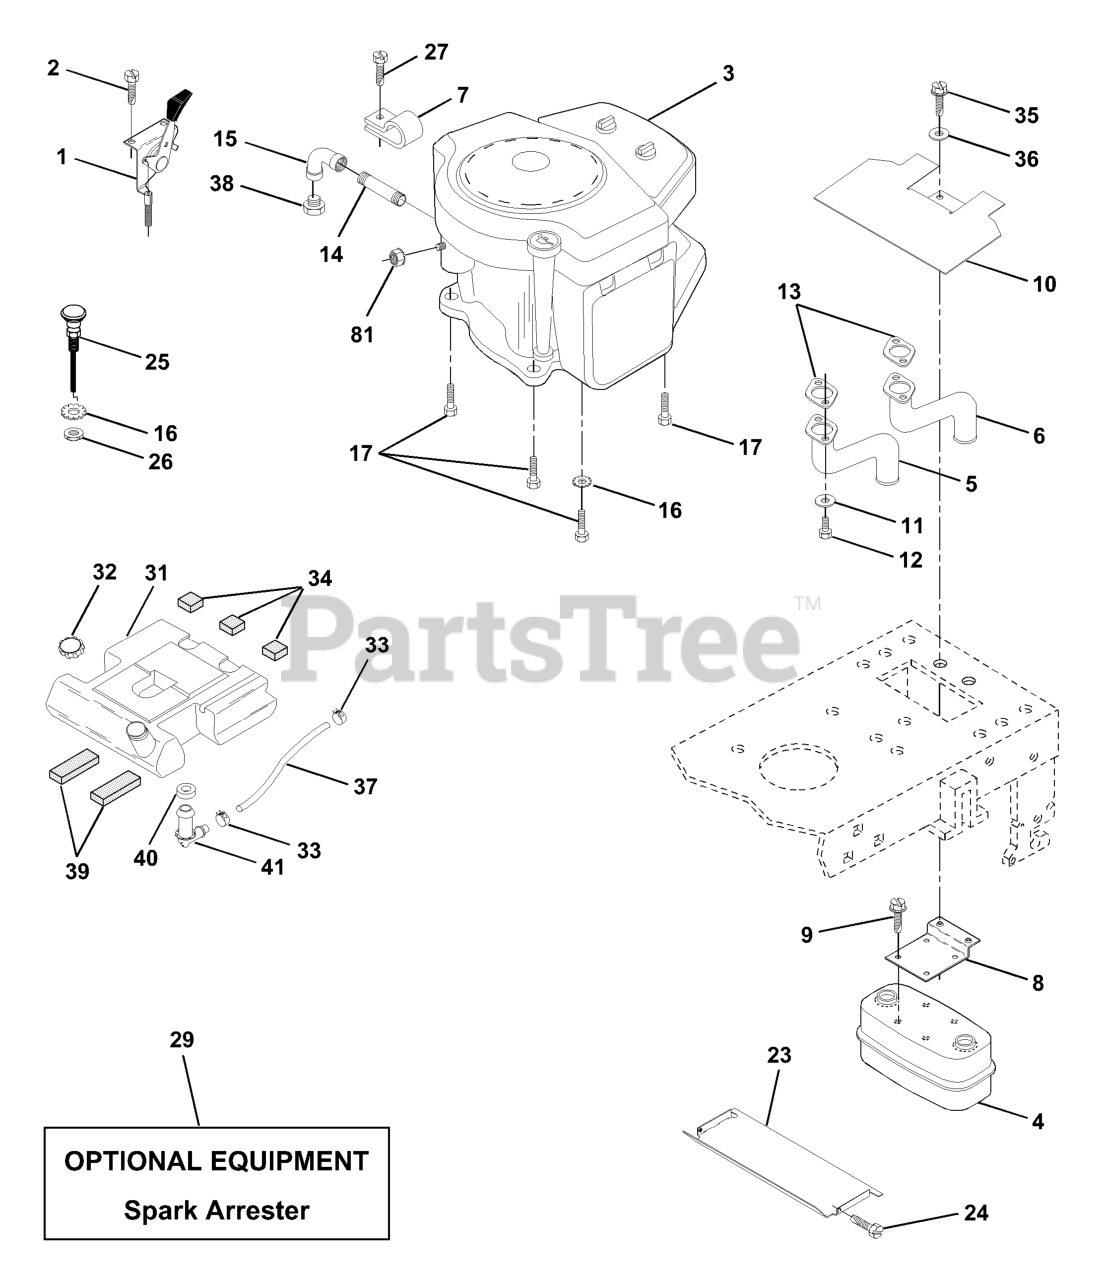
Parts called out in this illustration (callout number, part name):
1	CONTROL.THROT.RH.BLK.FLG.44.75
2	SCREW LT
4	MUFFLER
5	EXHAUST ASM. LEFT
6	EXHAUST ASM. RIGHT
8	BRACKET MUFFLER
9	SCREW ST
10	SHIELD HEAT LT
11	LOCKWASHER
12	BOLT
13	GASKET (B&S 692282)
14	Nipple Pipe 3/8 Npt X 4-1/2"
15	ELBOW
16	LOCKWASHER
17	SCREW LT
23	HEAT SHIELD
25	CONTROL.CHOKE.51.00.BLK.W/BEND
26	NUT
29	KIT.SPARK ARRESTOR 794945 B&S
31	FUEL TANK
32	FUEL CAP
33	HOSE CLAMP
34	PAD-SPACER LT
35	SCREW.THDROL.5/16-18X3/4.TTY
36	WASHER
37	FUEL LINE 54"
38	Plug Oil Drain
39	PAD IDLER TI
40	BUSHING OUTLET T
41	STEM FUEL TANK
81	NUT
